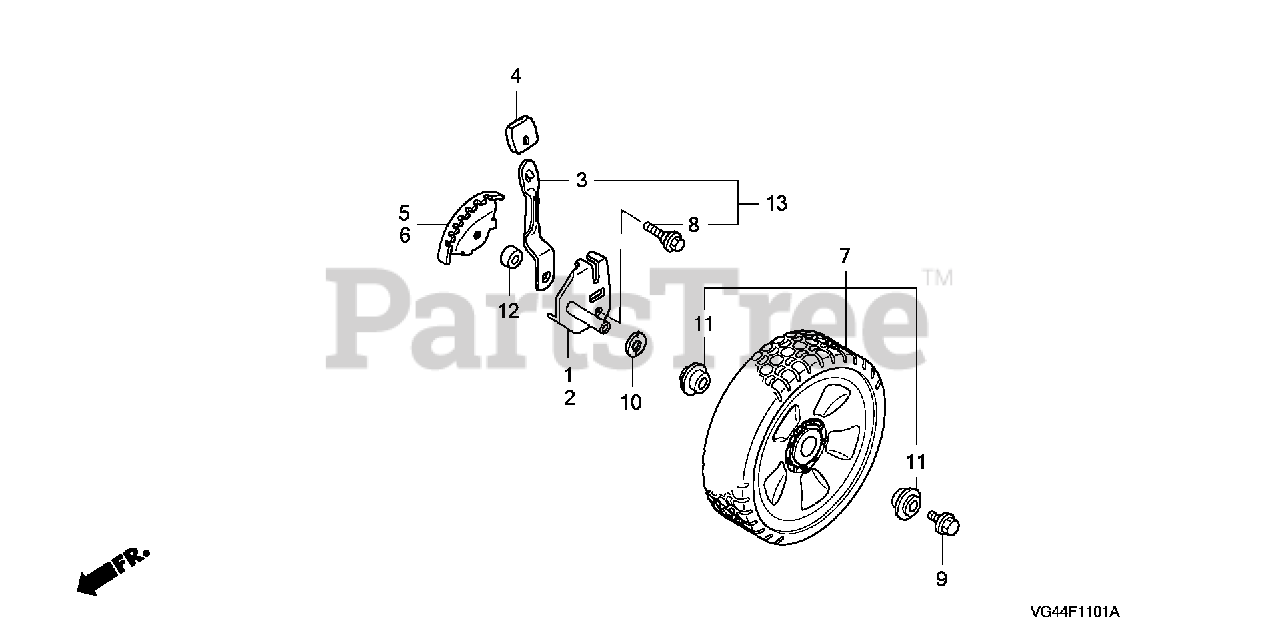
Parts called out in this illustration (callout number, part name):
1	ARM, R. FR. ADJUSTING
2	ARM, L. FR. ADJUSTING
3	PLATE, FR. ADJUSTER
4	GRIP, ADJUSTER *NH164* (GRIP GRAY)
4	GRIP, ADJUSTER
5	PANEL, R. FR. ADJUSTING
6	PANEL, L. FR. ADJUSTING
7	WHEEL, FR. *NH164* (GRIP GRAY)
8	PLATE KIT, FR. ADJUSTER
8	BOLT, ADJUSTER ARM
9	BOLT, WHEEL
10	WASHER, WHEEL
11	BEARING, RADIAL BALL
11	BEARING, WHEEL
12	COLLAR, FR. ADJUSTING
13	PLATE KIT, FR. ADJUSTER
